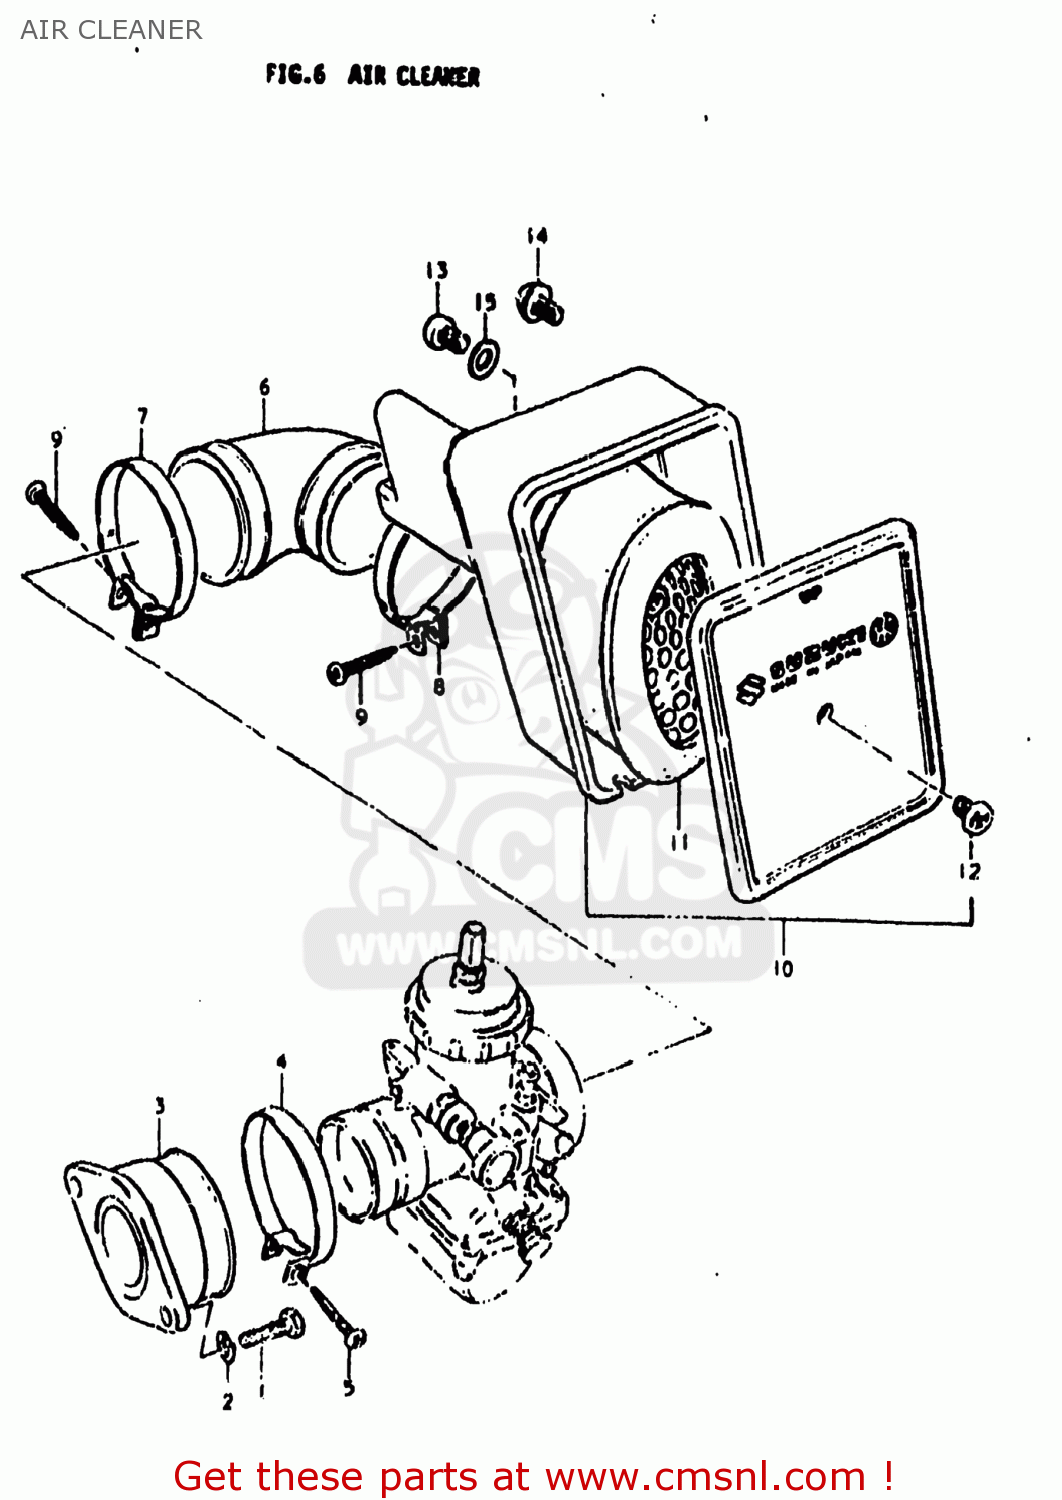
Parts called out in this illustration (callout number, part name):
1	BOLT
2	LOCK WASHER
3	PIPE,INTAKE
4	CLAMP
5	SCREW
6	HOSE,CARBURETOR AIR INLET
7	CLAMP
8	CLAMP
9	SCREW
10	CLEANER ASSY,AIR
11	FILTER
12	SCREW
13	SCREW
14	SCREW
15	WASHER
